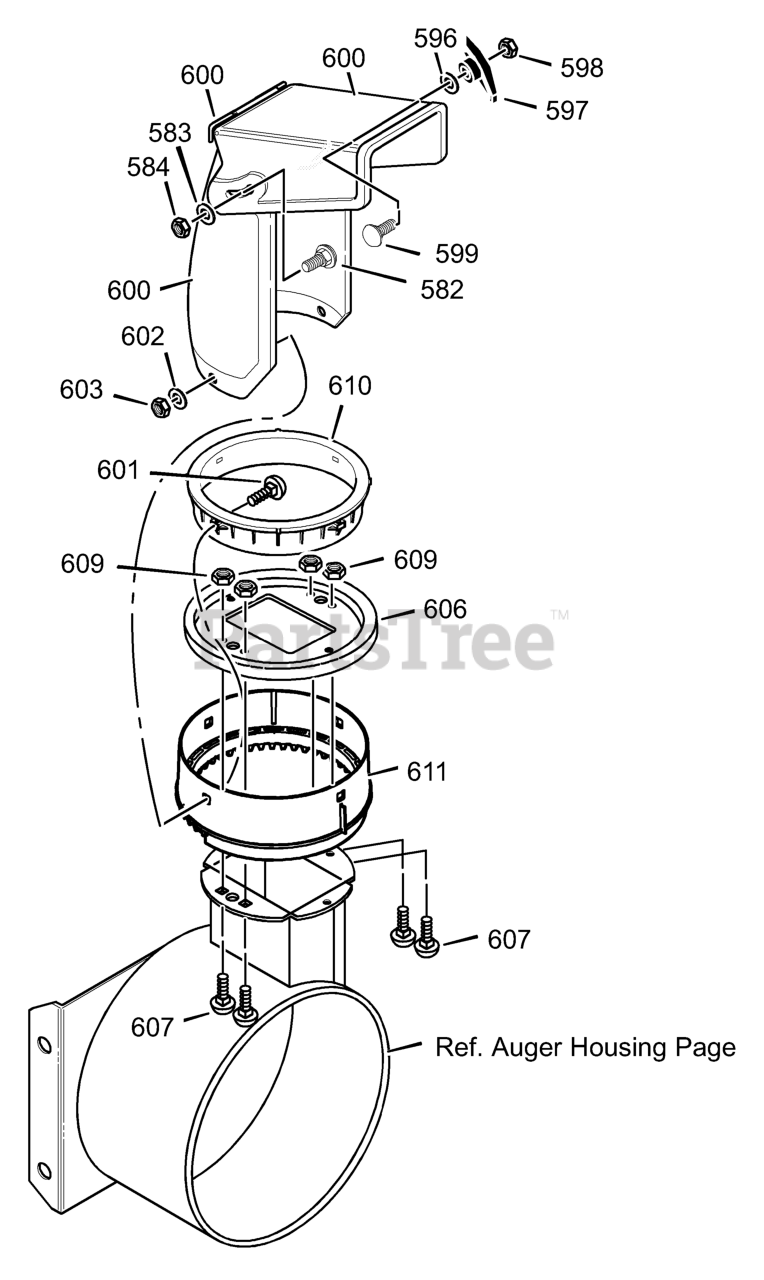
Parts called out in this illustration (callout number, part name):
582	SCREW, 5/16-18 x 1.00
583	WASHER, FLAT
584	NUT, 5/16-18
596	WASHER
597	KNOB, T 3.00
598	NUT, 5/16-18
599	BOLT, 5/16-18X1..00
600	CHUTE ASSEMBLY
601	BOLT, 5/16-18
602	WASHER, FLAT
603	NUT, 5/16-18
606	CHUTE COLLAR
607	SCREW, 1/4-20 X 0.75
609	NUT, 1/4-20 HEX NYLOCK
610	RETAINER RING INNER
611	RETAINER RING OUTER
